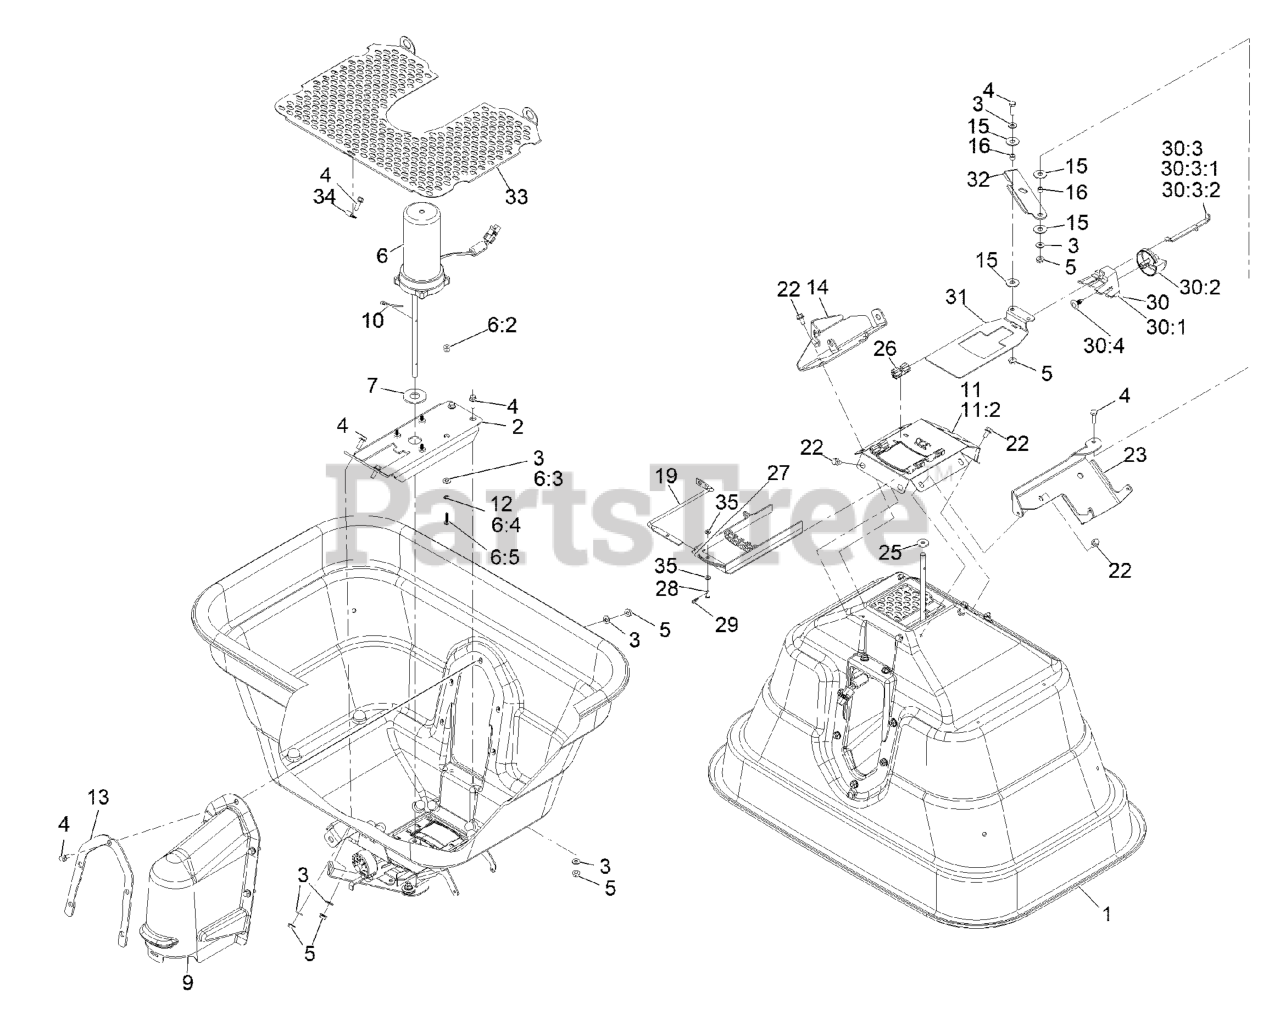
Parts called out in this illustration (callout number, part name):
1	Hopper-Spreader, 175 Lb
2	BRACKET-MOUNT, MOTOR
3	WASHER-FLAT
4	SCREW-HH
6	SPREADER MOTOR ASM
6:2	SPACER-FLANGED
6:3	WASHER-FLAT
6:4	WASHER-LOCK, INT
6:5	SCREW-SHWH
9	COVER-MOTOR
10	WIRE-AGITATOR
11	HOPPER PLATE W/ BEARING ASM
11:2	HOPPER BOTTOM BEARING
12	WASHER-LOCK, INT
13	FLANGE-COVER, MOTOR
14	BRACKET-HOPPER, GATE CONT
19	ROD-CONTROL, DIFFUSER
22	SCREW-HHF
23	BRACKET-LEVER, HOPPER GATE
25	WASHER-FELT
26	GUIDE-RATE, GATE
27	DIFFUSER
28	PIN-CLEVIS
29	PIN-COTTER, HAIR
30	RATE DIAL ASM
30:1	MOUNT-DIAL
30:3	Rate Gate Link ASM
30:3:1	LINK-GATE, RATE
30:3:2	SCREW-SHOULDER, SLOTTED
30:4	Footpad Fastener
31	RATE GATE
32	LEVER-GATE
33	SCREEN-HOPPER, LARGE HOLE
33	SCREEN-HOPPER, MEDIUM HOL
33	SCREEN-HOPPER, SMALL HOLE
34	CLAMP-LOOP
35	WASHER-FLAT
